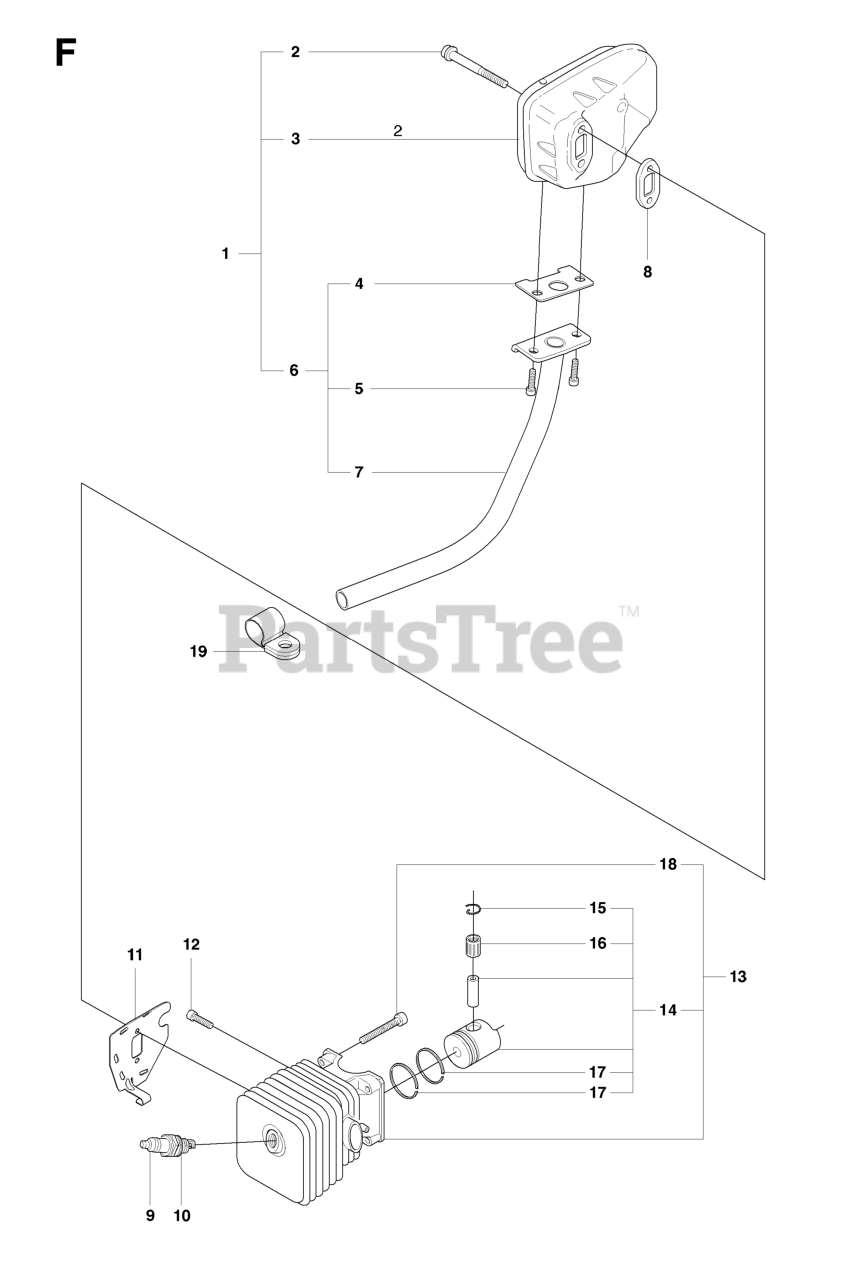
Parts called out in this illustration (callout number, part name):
4	GASKET EXHAUST PIPE
9	SPARK PLUG RCJ7Y
10	SPARK PLUG M14X1.25 NGK BPMR7A
11	AIR CONDUCTOR
12	SCREW M5X14
13	PISTON
17	PISTON RING
18	SCREW MC6S 5X35
